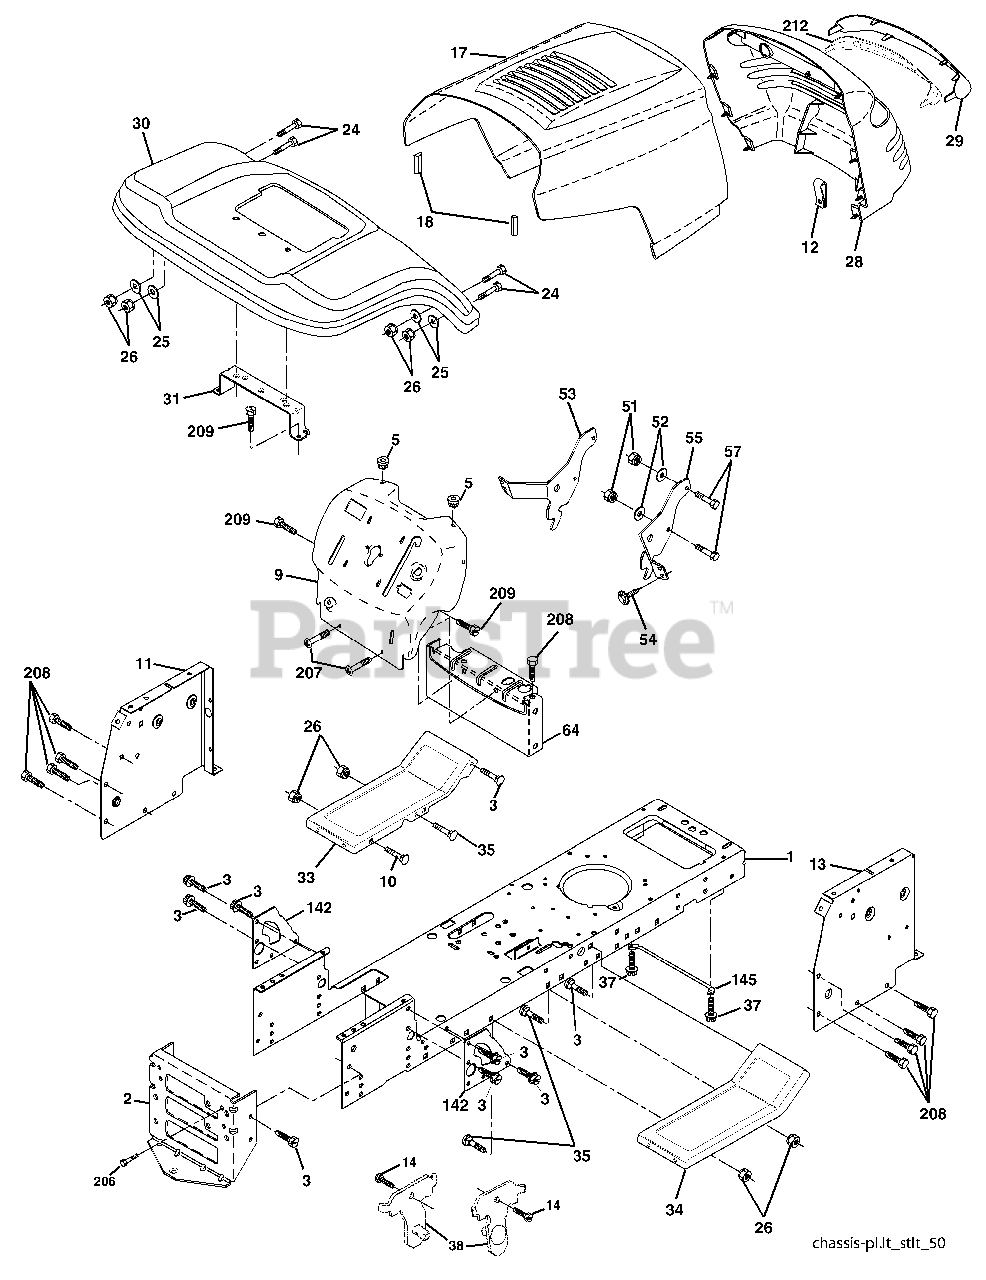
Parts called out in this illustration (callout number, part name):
1	Chassis
2	Drawbar
3	Screw 3/8-16x.75
5	Bumper Hood/Dash
10	Bolt Carriage 3/8-16 x 1
11	Panel Dash Lh
12	Clip Tinnerman
13	Panel Dash Rh
14	Screw Thdrol 3/8-16 x 1-1/4
17	Hood LT/PL
18	Bumper Hood
24	Bolt Fin Hex 3/8-16 x 1 Gr 5
25	Washer 13/32 X 13/16 X 12 Ga
26	Nut Lock Hex W/Ins 3/8-16 Unc
28	Grille LT/PL
29	Lens LT/PL
30	Fender Footrest STLT Pnt
31	Bracket Support Fender
33	Footrest Pnt Lh
34	Footrest Pnt Rh
35	Bolt Rdhd Sht Sqnk 3/8-16 x 3/4
37	Screw Thdrol 6/16-18 x 1/2 TYT
38	Bracket Asm. Pivot Mower Rear
51	Nut Lock Hex W/Ins 1/4-20
52	Washer 9/32 x 7/8 x 16 Ga.
53	Bracjet Grukke Lh
54	Screw Hex Wshd 8-18 x 7/8
55	Bracket Grille Rh
57	Bolt Hex 1/4-20 x 3/4
64	Dash Lower STLT
142	Plate Reinforcement STLT
145	Rod Pivot Chassis/Hood
206	Bolt Shoulder 5/16-18
207	Screw Thdrol 5/16-18 x 1/2
208	Screw Thdrol 3/8-16 x 1/2
209	Screw Hex Wsh Thdr. 3/8-16 x 3/4
212	Insert Lens Reflect P/L LT
